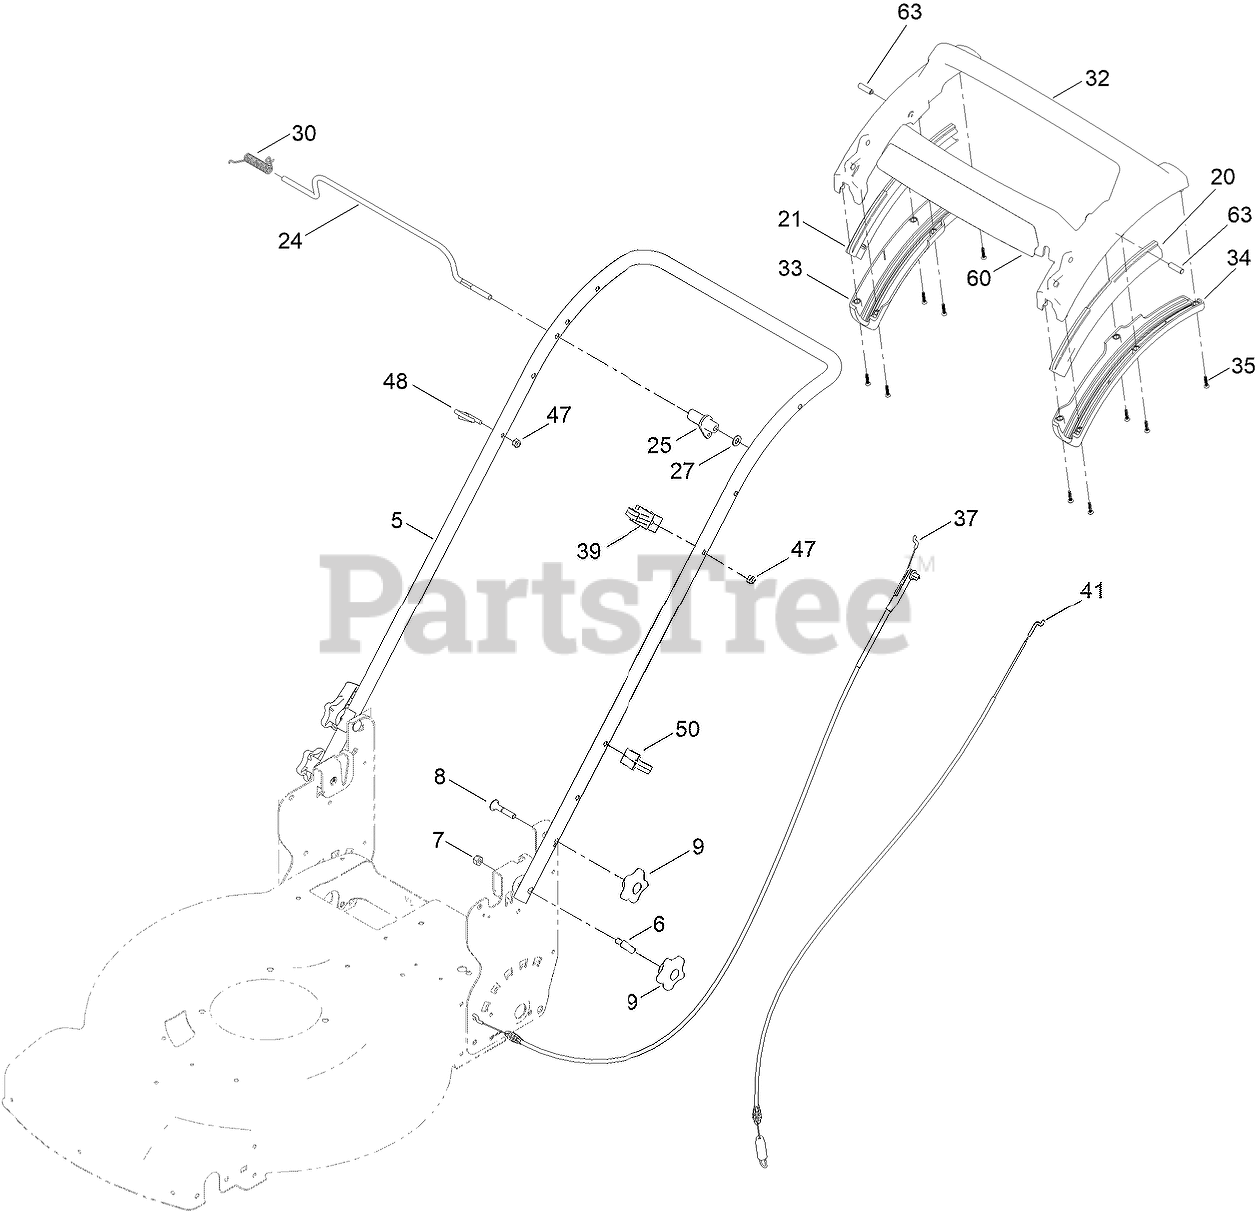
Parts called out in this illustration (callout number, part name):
5	HANDLE-CURVED
6	BOLT-SHOULDER, HANDLE
7	NUT-HEX
8	SCREW-CARR
9	KNOB-HANDLE
20	GUIDE-CURVED, LH (RWD)
21	GUIDE-CURVED, RH (RWD)
24	ROD-CONTROL, TRACTION
25	LEVER-TRACTION, RWD
27	WASHER-PLAIN
30	SPRING-TORSION
32	HANDLE-PERSONAL PACE, CURVED
33	BOTTOM-HANDLE, RH
34	BOTTOM-HANDLE, LH
35	SCREW-PPH
37	CABLE-BRAKE, PP BS
39	ANCHOR-CABLE, RWD
41	CABLE-TRACTION, RWD (PP)
47	NUT-HEX
48	GUIDE-ROPE
50	GUIDE-CABLE
60	DECAL - ADS, HANDLE
63	PIN-HANDLE, PP
